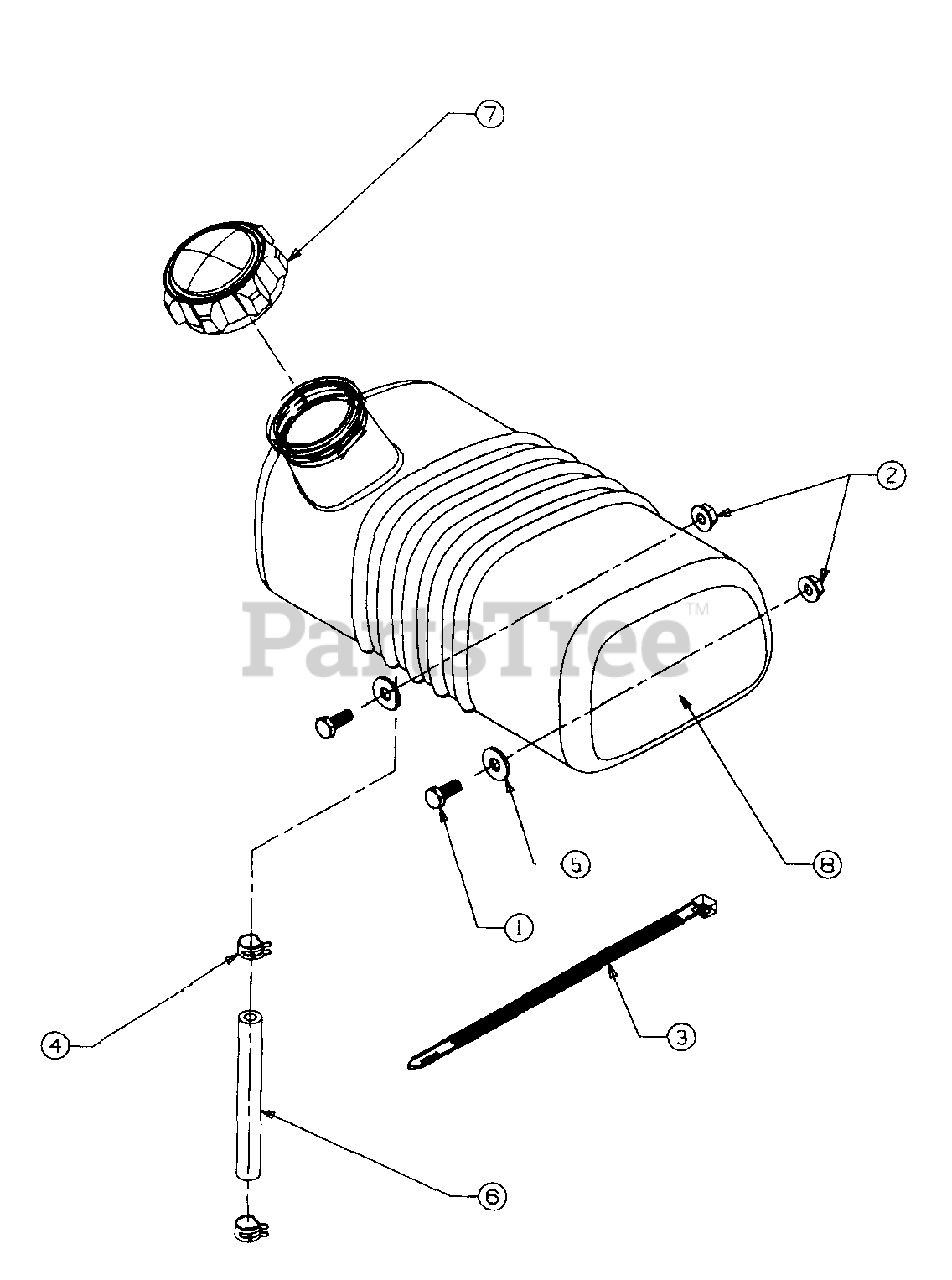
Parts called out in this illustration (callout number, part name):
1	SCREW - HEX
2	NUT - HEX LOCK FLANGE
3	CABLE TIE
4	CLAMP - HOSE
5	WASHER - FLAT
6	HOSE - FUEL LINE 12"
7	CAP - FUEL
8	TANK - FUEL 1 GALLON
